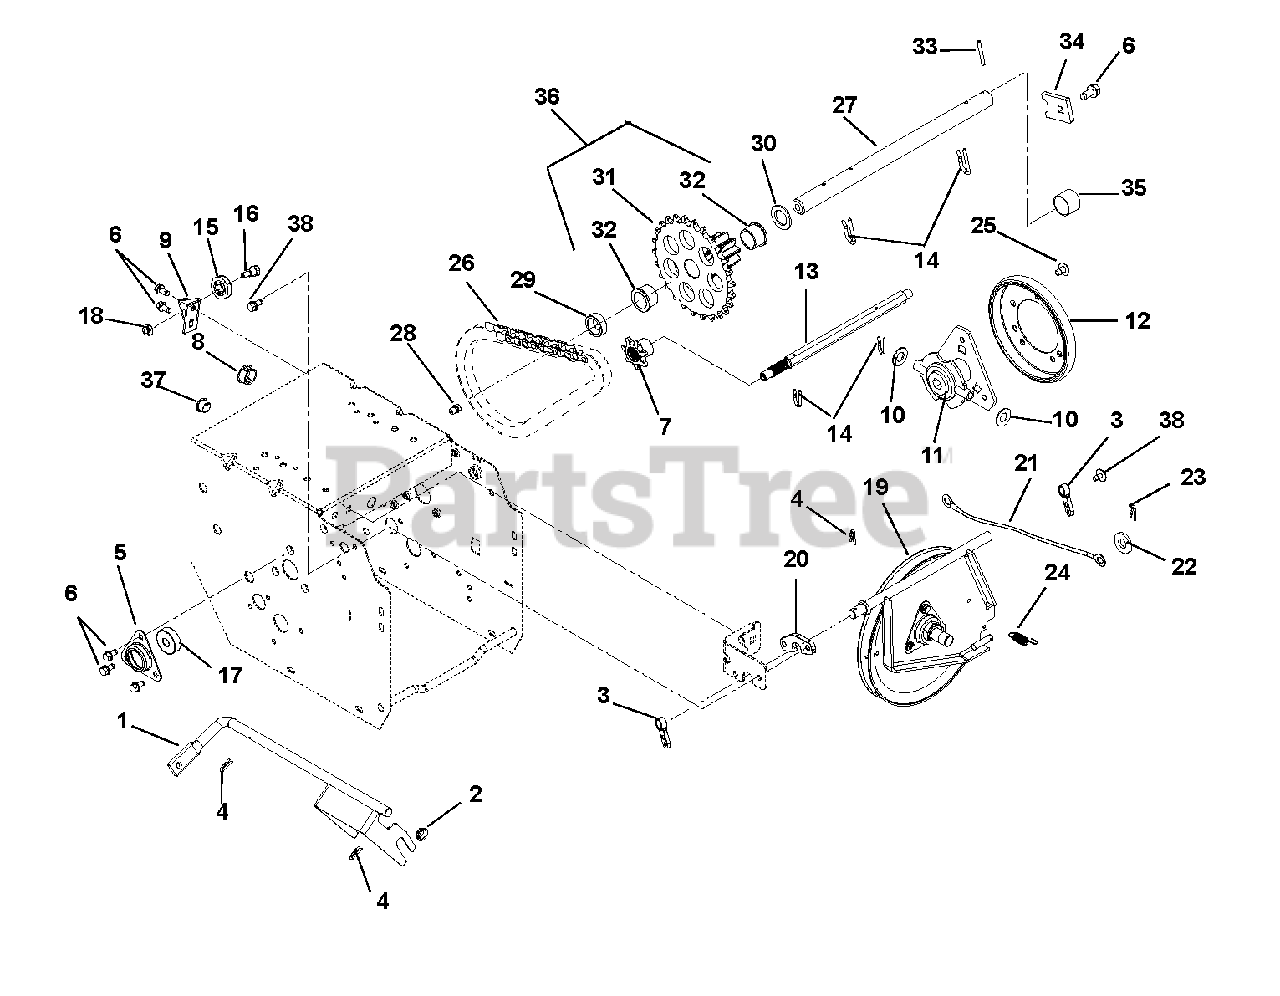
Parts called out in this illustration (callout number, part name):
1	Shift Fork
2	Bushing, Polyliner
3	Support Bushing, Swing Gate
4	Clip, Spring
5	Flange, Bearing
6	Screw, Tapping Hex Washer Head Thread Rolling .25-20 x .50
7	Sprocket, Pinion
8	Plug, Hole
9	Bracket, Cable Pulley
10	Washer, Flat Steel .505 x 1.00 x .062
11	Carrier, Friction Disc
12	Friction Disc
13	Hex Shaft
14	Pin, Spring Clip
15	Pulley, Cable
16	Bolt, Shoulder
18	Nut, Locking Top Flange .25-20
19	Plate, Swing Assembly
22	Washer, Flat Steel .344 x .688 x .065
23	Pin, Hair Internal .08 x .18 x 1.18
25	Screw, Tapping Serrated Round Head Torx .31-18 x .50
26	Chain, Roller
27	Shaft, Pinion
28	Zerk, Fitting .25 x .125 Drive-In
29	Bushing, Sleeve
30	Washer, Flat Steel .630 x 1.005 x .062
31	Sprocket/Gear (Included in Item 36)
32	Bushing, Flange (Included in Item 36)
33	Pin, Groove, Type E .125 x 1.00 Alloy
34	Tab, Anti-Rotation
36	Sprocket/Gear w/Bushings (Includes Items 31 and 32)
37	Bushing, Polyliner
38	Screw, Tapping Hex Washer Thread Rolling .25 -20 x .75
